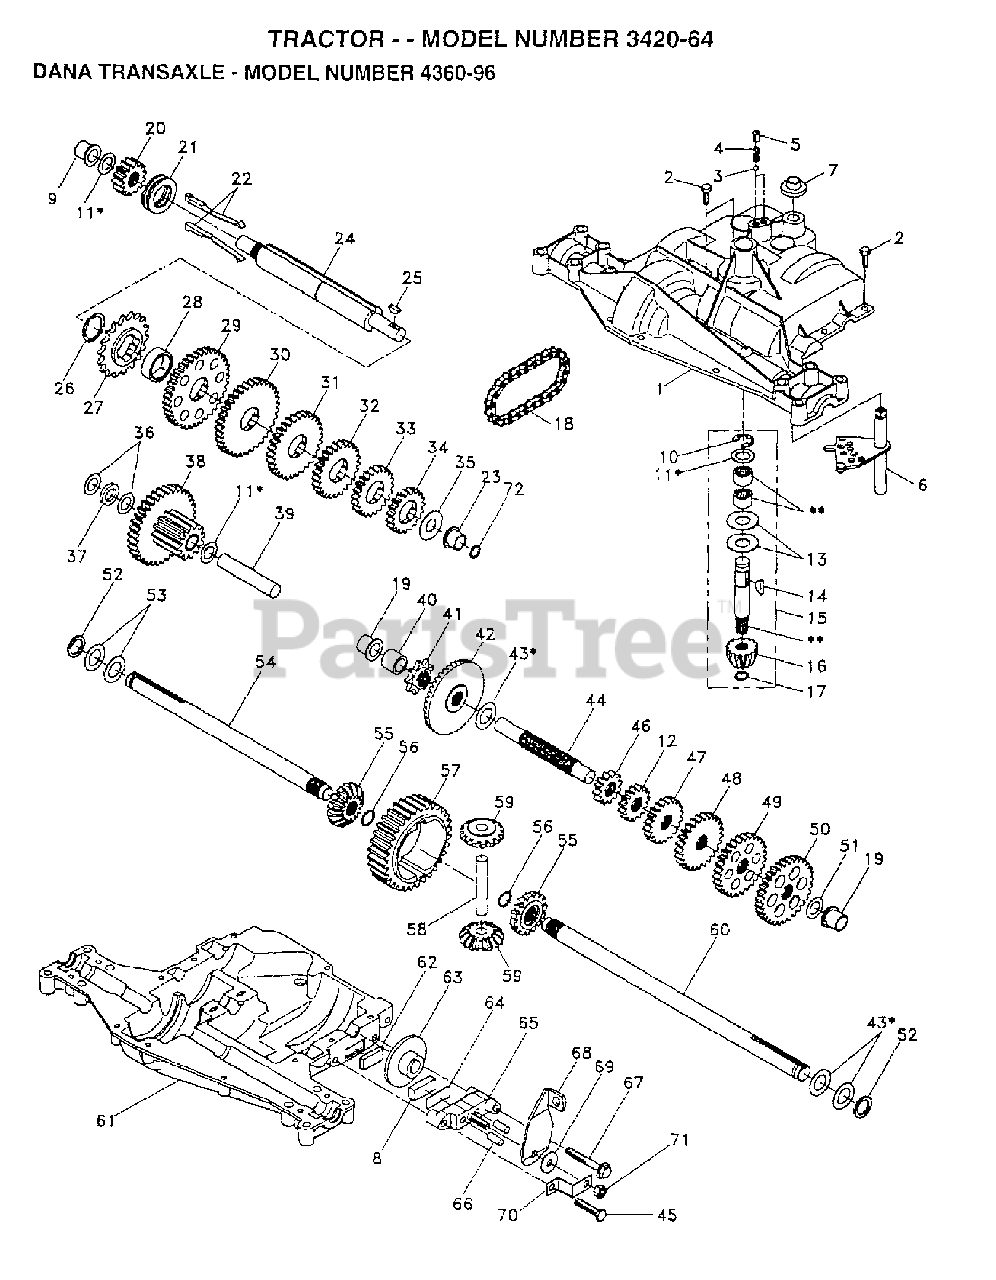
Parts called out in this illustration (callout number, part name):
1	IGNITION HARNESS
2	Poulan TBD
4	SPRING, DETENT
6	SHIFTER KIT
7	BOOT, SHIFTER
8	PUCK, FRICTION
10	Poulan TBD
11	SHIM.KIT.DANA.4689
12	PLUG PLASTIC
13	WASHER.PLAIN..632X1.38X.046
14	KEY.WOODRUFF.DANA
15	ASSY, KIT INPUT SHAFT
16	PIN, BEVEL, 14T YT
17	RING RETAINING
18	CHAIN 24 PITCH LT
19	BEARING, FLANGE LT
20	GEAR SPUR 14 TTH
23	BEARING.FLANGE (DANA 5511)
24	SHAFT INTERM DANA
26	RING, RETAINING LT
27	SPROCKET 18T
29	GEAR, SPUR 37 TEETH
30	GEAR, SPUR 35 TEETH
32	GEAR, SPUR 25 TEETH
33	GEAR, SPUR 22 TEETH
36	WASHER 025
38	ASSM GEAR COMB T NLA
39	SHAFT IDLER
41	SPROCKET 9T LT
42	GEAR, SPUR 42T YT
44	SHAFT, DRIVE
46	GEAR SPUR 12 TEETH
49	GEAR, SPUR 28 TEETH
50	GEAR, SPUR 31 TEETH
52	NEOPRENE.WASHER.DANA
53	WASHER 031
54	AXLE T, LH
55	GEAR 15T T
56	RING, RETAINING
59	GEAR 1ST T
61	LOWER HOUSING
62	PUCK, FRICTION
63	BRAKE DISC T
64	SPACER LT
65	JAW T
67	SCREW, SELF TAPPING, LARGE
69	WASHER, PLAIN .321 X 1.00X.055
70	BRACKET, ANTI ROTATION
71	LOCKNUT
73	SHELL, GREASE
